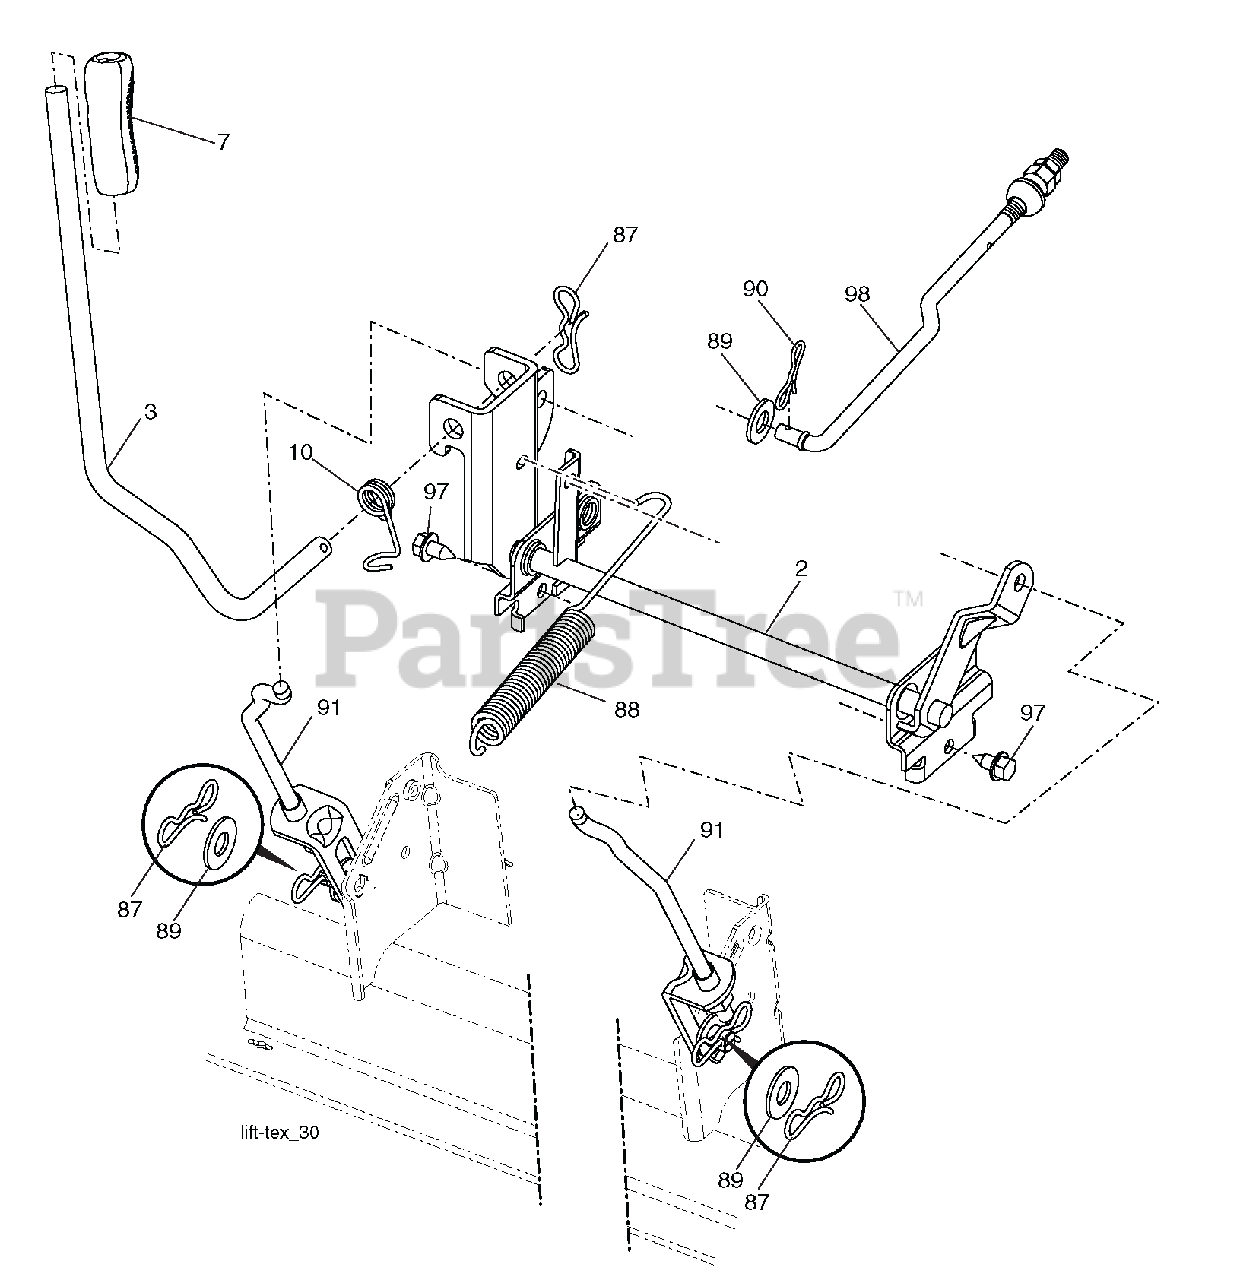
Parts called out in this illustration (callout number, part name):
2	SHAFT ASM., LIFT
3	LEVER.LIFT.HANDLE.LT
7	GRIP LEVER 5625 LD BLACK 428
10	SPRING.TORSION.HANDLE.LIFT
87	PIN.COTTER.7/16.BOW TIE LOCK
88	SPRING.LIFT ASSIST
89	WASHER.CLEAR ZINC
90	PIN.COTTER.5/16.BOW TIE LOCK
91	LINK ASM.LIFT.LH.REAR
97	SCREW.HEXWSH THDR3/8-16X3/4.BL
98	LINK ASM.SUSP.FRONT.MWR.11
